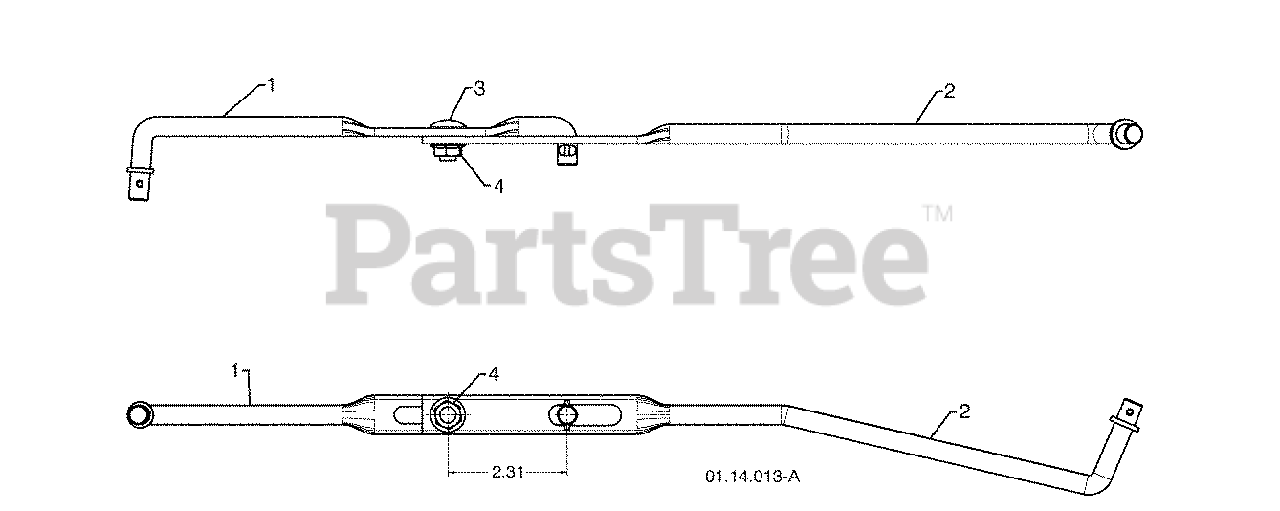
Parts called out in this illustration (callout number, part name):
1	SHIFTER ROD TOP
2	SHIFTER ROD BOTTOM
3	CARRIAGE BOLT 5/16-18 X .75
4	NUT 5/16-18
